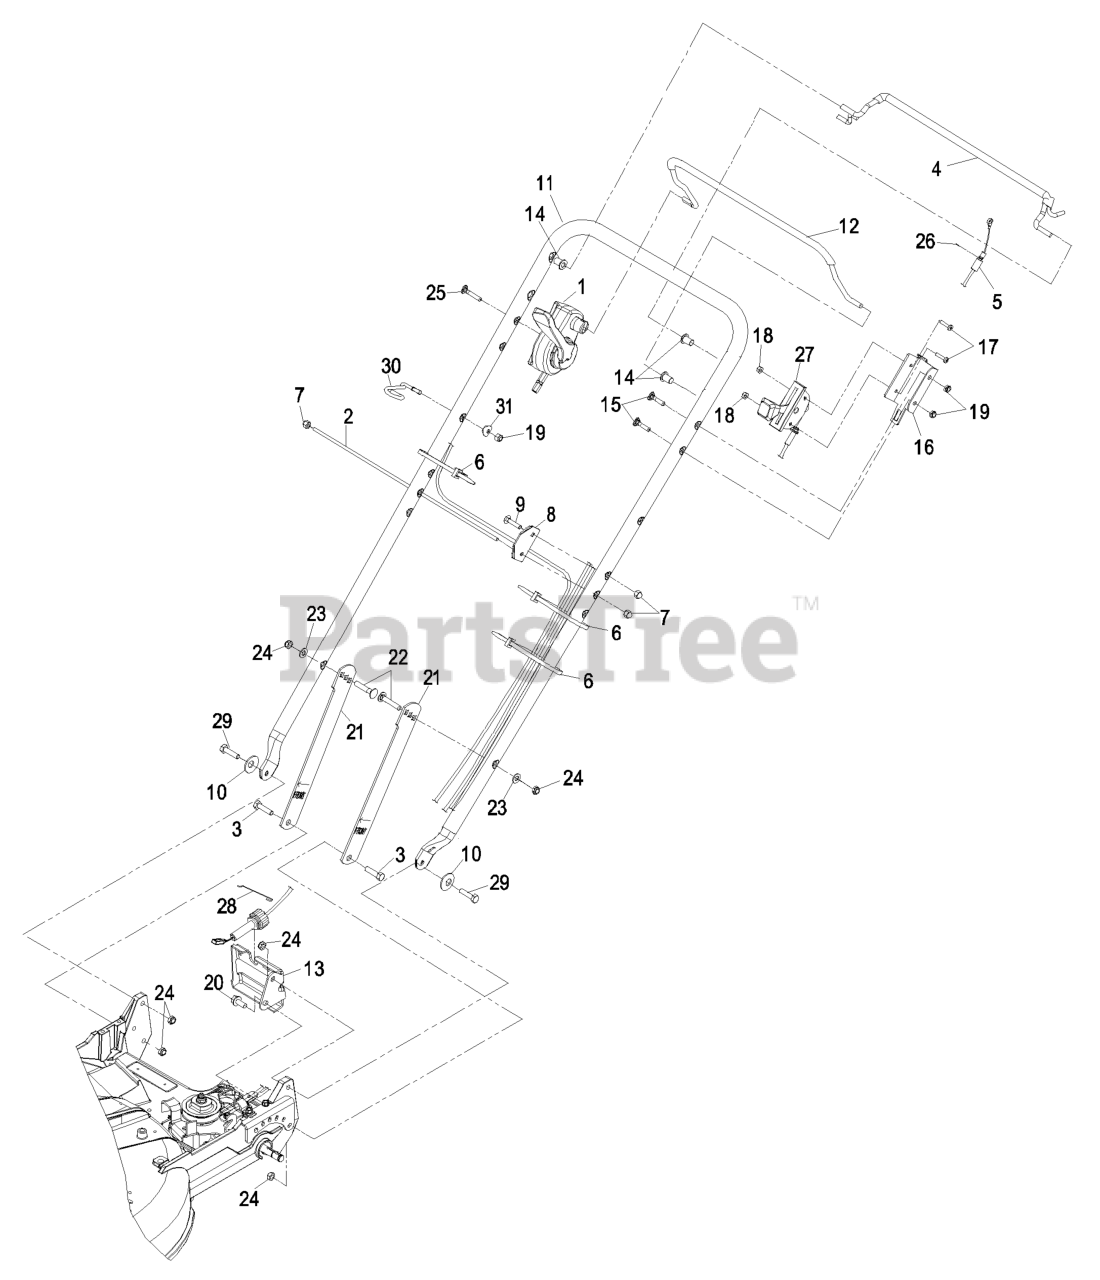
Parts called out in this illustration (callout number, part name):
1	CONTROL,BBC METRO 21
2	ROD, BAG SUPPORT
3	SCREW-HH
4	ASM,TRACTION BAIL W/GRIP
5	CABLE,TRACTION M21
6	TIE-CABLE
7	NUT-CAP
9	SCREW-CARR
10	WASHER-BELLEVILLE
11	HANDLE M21
12	BAIL, BBC COATED
13	BRACKET-ADJUSTMENT, TRACT
14	BUSHING
15	BOLT-HANDLE
16	BRACKET, THROTTLE
17	SCREW-PPH
18	NUT-LOCK, NI
19	NUT-LOCK, NI
20	Screw-HWH 5/16-18 X 3/4 Tf
21	LATCH,HANDLE
22	BOLT-CARR
23	WASHER-PLAIN
24	NUT-LOCK, NI
25	SCREW-HH
27	CABLE,THROTTLE KAWASAKI
28	RETAINER-CABLE
29	SCREW-HH
30	GUIDE-ROPE
31	WASHER
